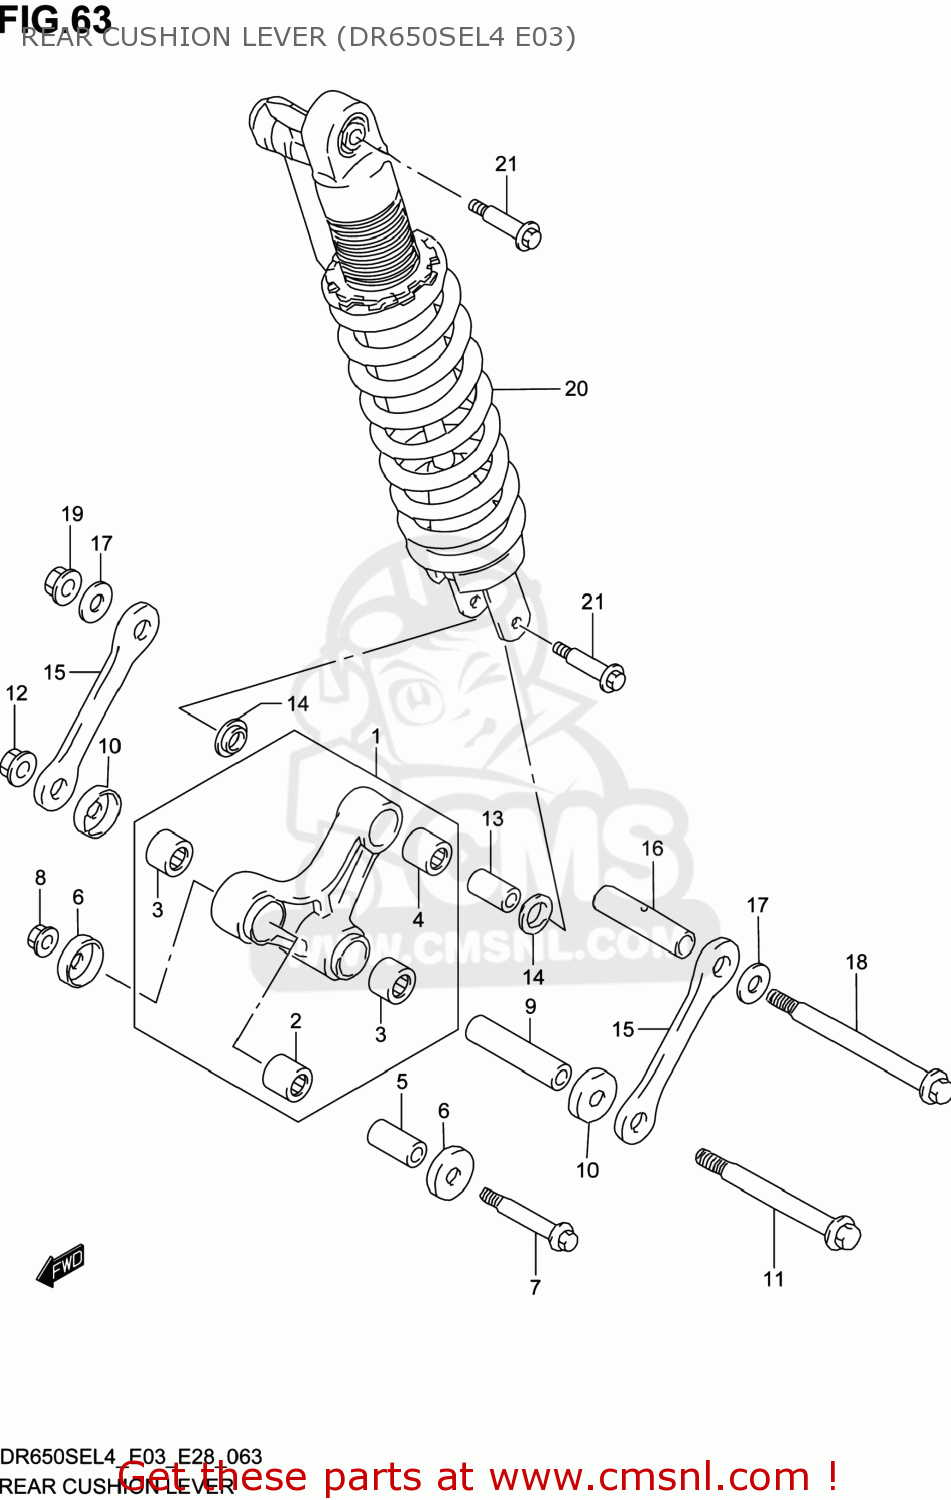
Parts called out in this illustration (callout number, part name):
1	LEVER SET,RR CUSHION
2	BEARING(20X27X30)
3	BEARING(21X27X20)
4	BEARING(17X24X20)
5	SPACER,RR CUSHION LEVER FR
6	SEAL,RR CUSHION LEVER FR DUST
7	BOLT,RR CUSHION LEVER FR
8	NUT
9	SPACER,RR CUSHION LEVER CTR
10	SEAL,RR CUSHION LEVER CTR
11	BOLT,RR CUSHION LEVER CTR
12	NUT
13	SPACER,RR CUSHION LEVER
14	SEAL,RR CUSHION LEVER RR DUST
15	ROD,RR CUSHION LEVER
16	SPACER,RR CUSHION LEVER CTR
17	WASHER
18	SHAFT,RR CUSHION LEVER FR
19	NUT
20	ABSORBER ASSY,RR SHOCK
21	BOLT,RR CUSHION ROD UPR
